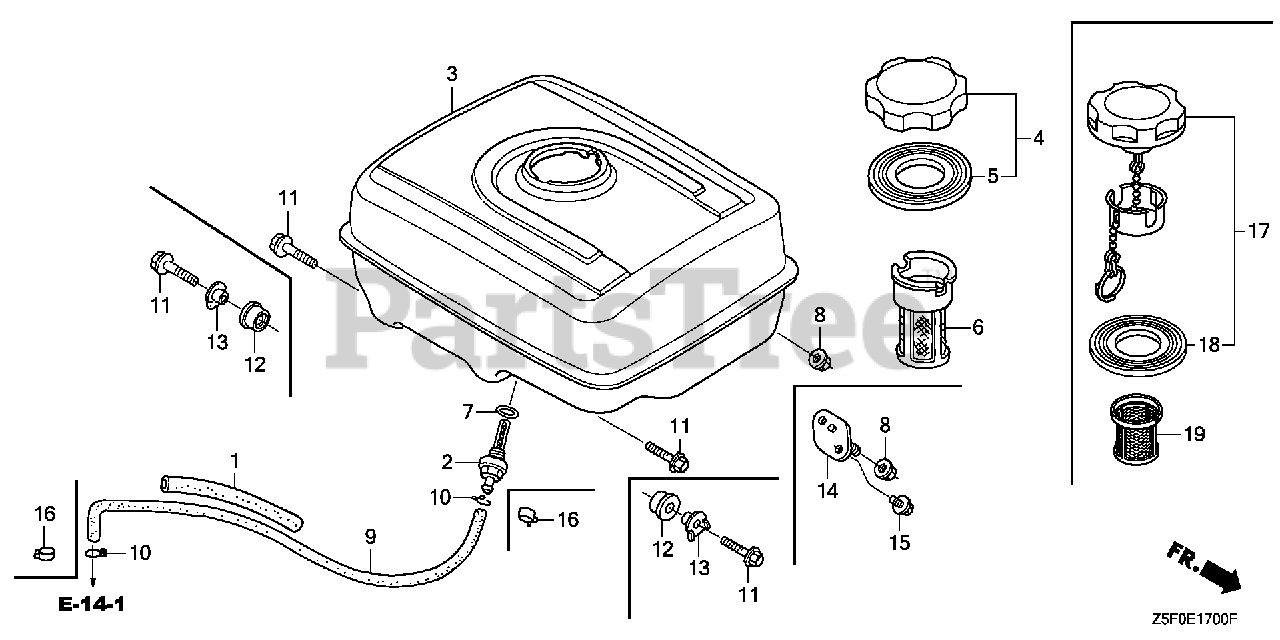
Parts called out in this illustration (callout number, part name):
1	RUBBER, SUPPORTER (107MM)
2	JOINT, FUEL TANK
3	TANK, FUEL *NH1* (BLACK)
7	O-RING (13.5X1.5) (ARAI)
7	O-RING (14MM) (NOK)
8	NUT, FLANGE (8MM)
9	TUBE, FUEL (4.5X210) (FKM)
11	BOLT, FLANGE (8X25)
16	CLAMP, TUBE (D8)
17	CAP, FUEL FILLER
18	GASKET, FUEL FILLER CAP (39X62X3) (RADICON)
19	FILTER, FUEL
